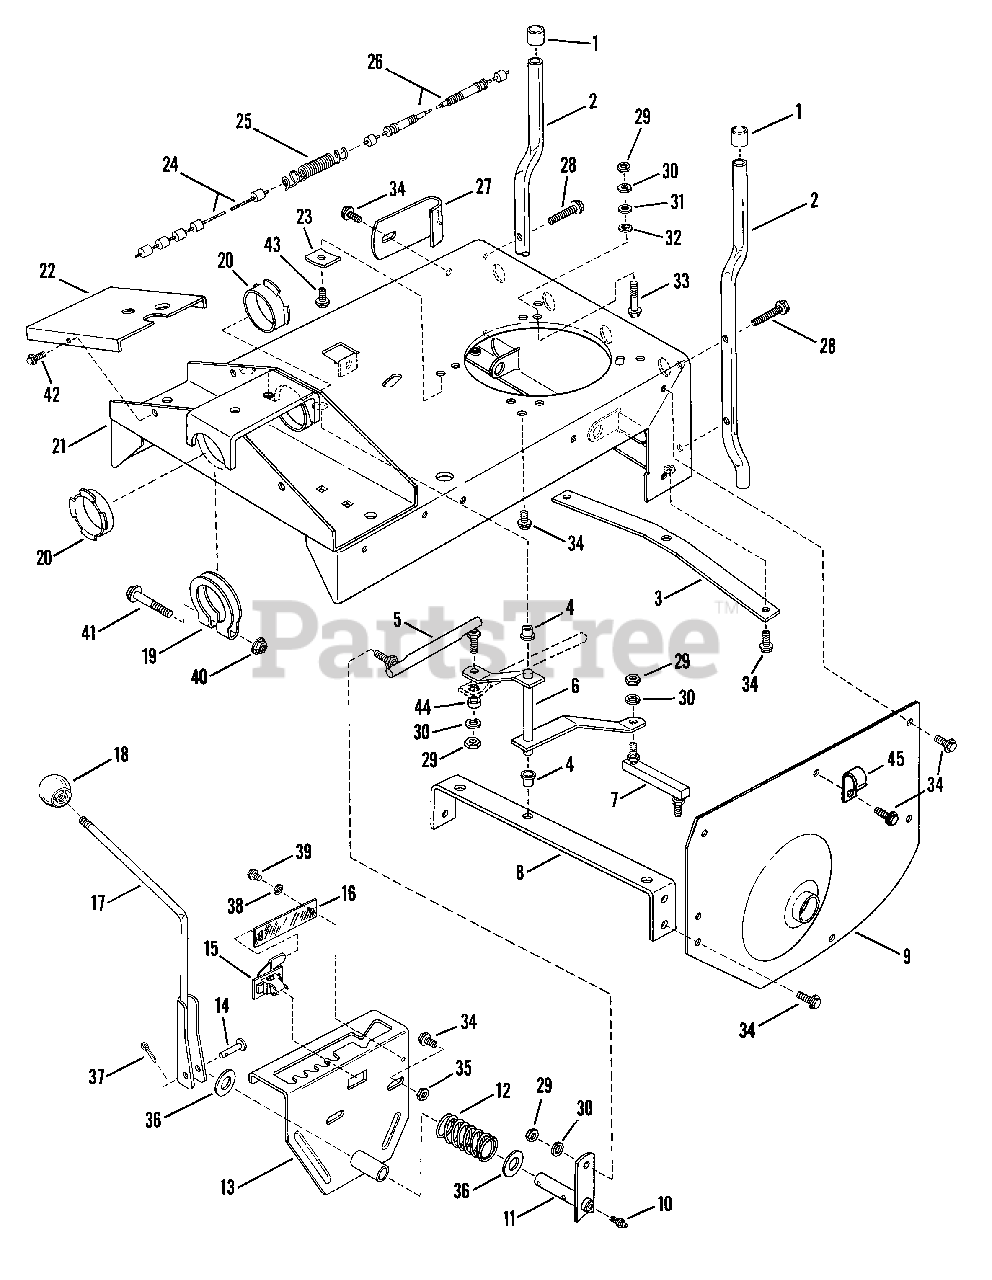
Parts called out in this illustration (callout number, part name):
1	CAP, Bumper
2	BUMPER, Rear
3	PLATE, Hitch
4	BUSHING, Nylon
5	LINK, Shift, Long
6	ARM, Shift
7	LINK, Shift, Short
8	BRACE, Cross
9	FENDER, Left Hand
10	FITTING, Lube (Press fit for .187 hole-no ball)
11	ARM, Shift Handle
12	SPRING, Shift Handle
13	DETENT, Shift
14	CLEVIS-PIN, 3/8x1 1/4
15	SWITCH, Interlock, Assembly
16	PROTECTOR, Switch
17	HANDLE, Shift
18	KNOB, Shifter Ball
19	CLAMP, Main Tube
20	GROMMET, Main Tube
21	MAIN-CASE
22	PANEL, Switch
23	WASHER, Clip (Tecumseh 5-6HP)
24	CABLE, Brake
25	SPRING, Brake Cable
26	HOUSING, Brake Cable
27	SUPPORT, Bumper
28	SCREW, Self-Tapping, 5/16-18x1 1/2
29	NUT, 5/16-24 Hex
30	LOCKWASHER, 5/16 Split
31	WASHER, 5/16 SAE Flat
32	RETAINER, Bolt
33	SCREW, 5/16-24x1 1/2 Hex Cap
34	SCREW, Self-Tapping, 5/16-18x5/8
35	NUT, 5/16-18 Hex
36	WASHER, Thrust
37	COTTER-PIN, 3/32x3/4
38	WASHER, #10 SAE
39	SCREW, #10-24 x 1/2" Hex Washer Self-Tap (Torx)
40	LOCKNUT, 5/16-24 Hex Flange
41	SCREW, 5/16-24x2 1/2 Hex Cap
42	SCREW, 1/4-20x3/8 Self-Tapping
43	SCREW, 3/8Cx1 Hex Self-Tapping
44	ROLLER
45	CLIP, Wire
